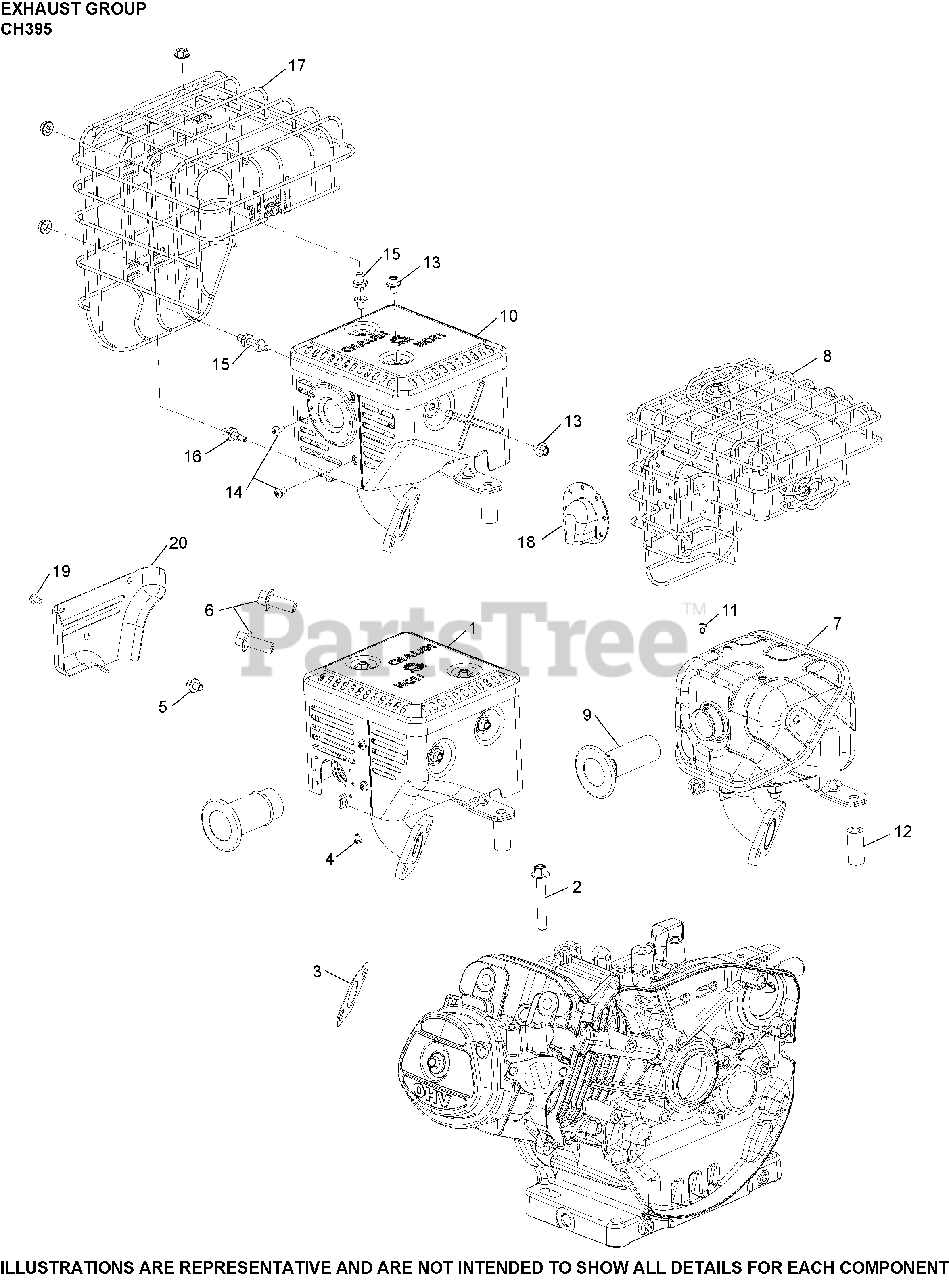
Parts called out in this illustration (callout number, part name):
2	SCREW, M8 X 55
3	GASKET, MUFFLER
6	SCREW, M10 X 25 (CKY)
9	ARRESTOR ASSEMBLY, SPARK
10	MUFFLER ASSEMBLY W/HEAT SHIELD
12	POST, MUFFLER BRACKET
14	SCREW, M5 X 8 (CKY)
